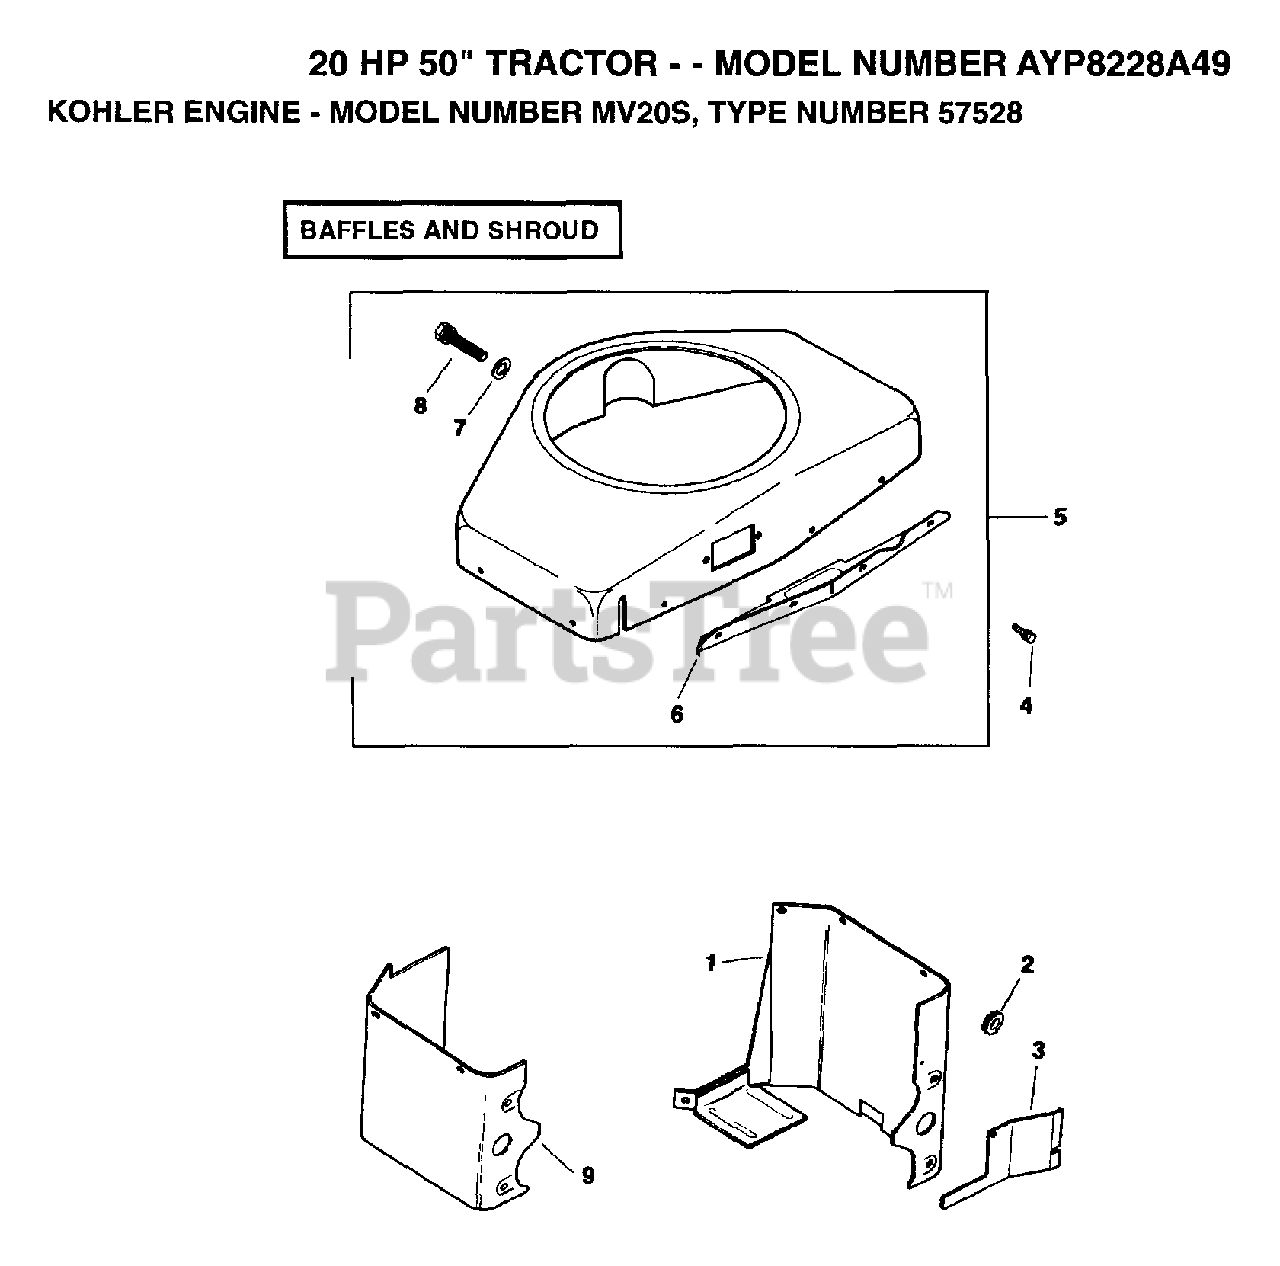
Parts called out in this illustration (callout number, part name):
1	BAFFEL, #2 HEAD
3	BAFFLE, FUEL PUMP
9	BAFFLE, #1 HEAD
